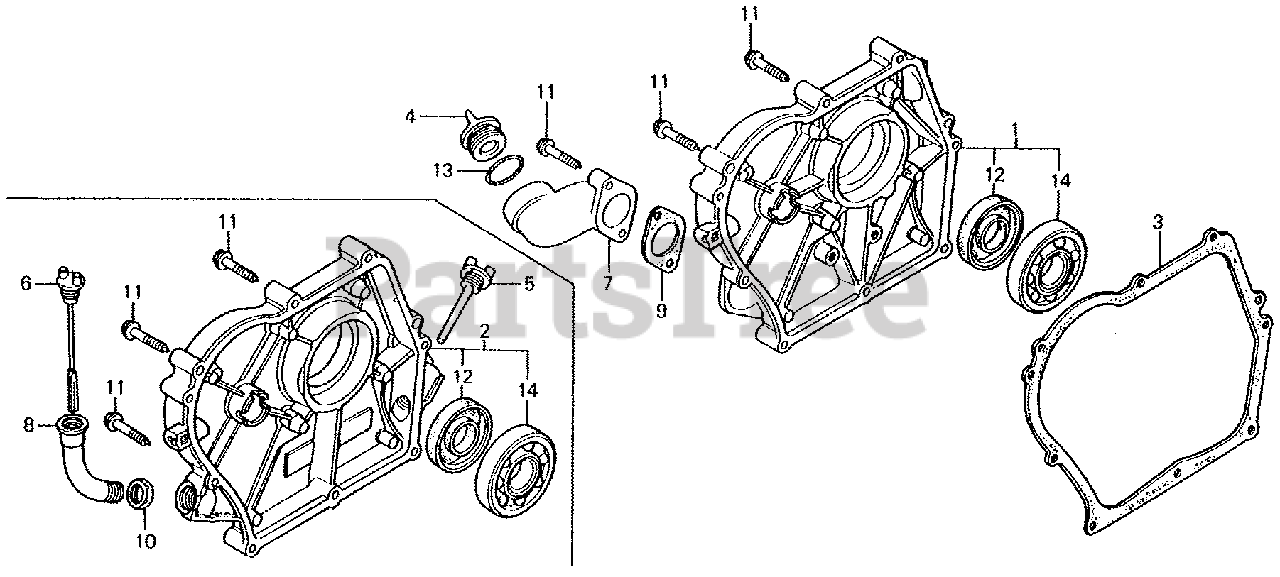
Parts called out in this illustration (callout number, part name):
1	COVER ASSY., CRANKCASE
2	COVER ASSY., CRANKCASE (S-TYPE)
3	GASKET, COVER
4	CAP, OIL
5	CAP, OIL
6	CAP, OIL
7	PIPE, OIL
8	PIPE, OIL
9	GASKET, OIL PIPE
10	NUT, OIL FILLER
11	BOLT, FLANGE (6X32)
12	OIL SEAL (25X41X6)
13	O-RING (26X2.7)
14	BEARING, RADIAL BALL (6205)
